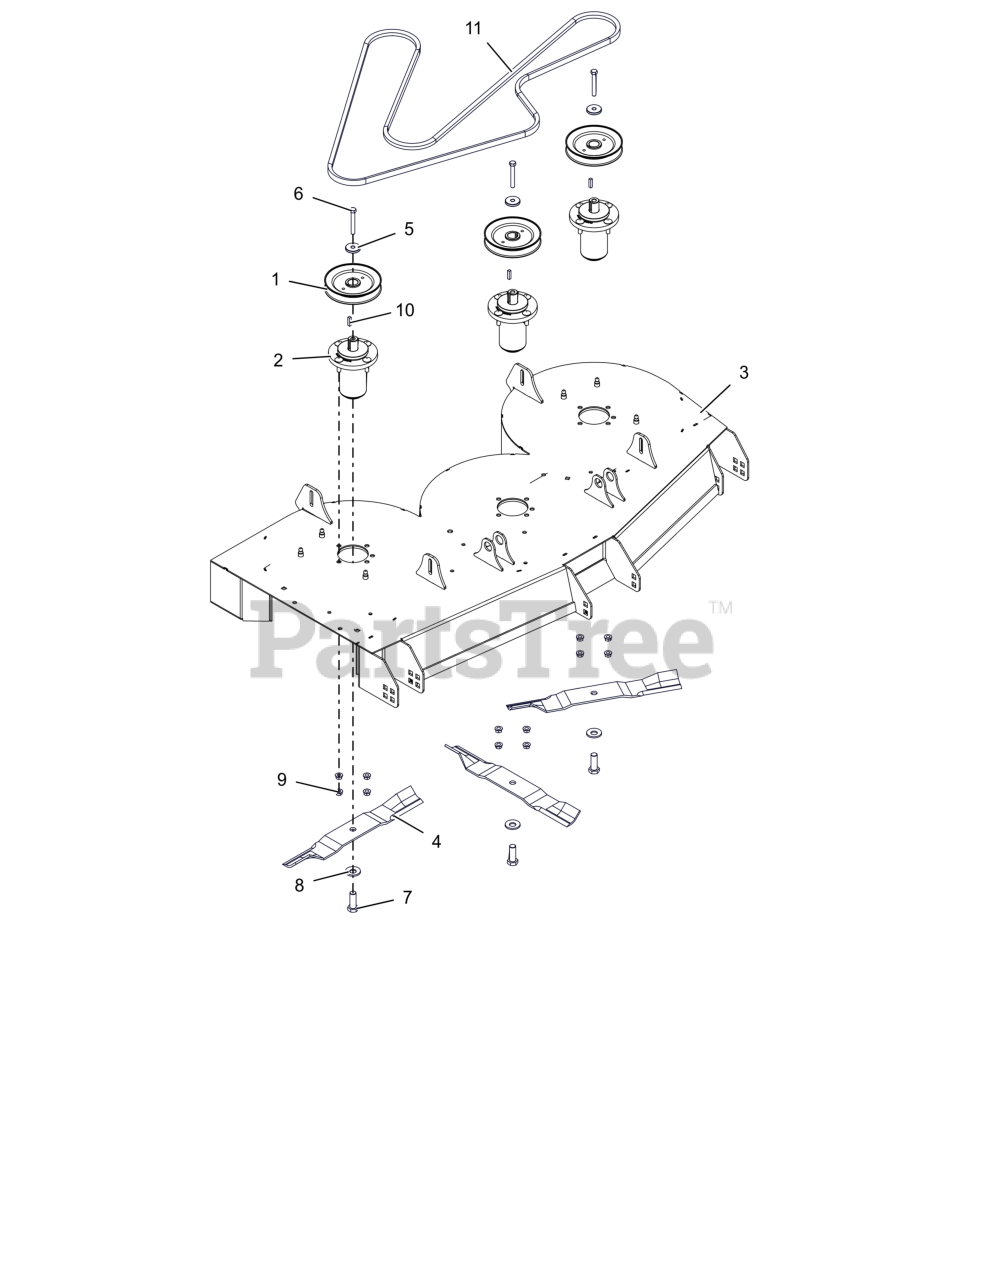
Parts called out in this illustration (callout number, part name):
1	PULLEY- V-1.000 ID X 5.750 OD
2	ASM, MAINT FREE ALUM SPINDLE
3	52 DECK WLDMT W/SAFETY DECALS
4	BLADE, 18"
5	RETAINER, SHEAVE
6	BLT, HEX .38-16X2.75 G8 ZCC
7	BLT, HEX .62-18X1.75 G8 ZCC
8	WSHR-BLVL .669X1.535X.138
9	NUT-LK-CTR-FLG .375-16 GF ZCC
10	KEY, SQ .25X.25X1.00 RC 40-50
11	V-BELT, B SECTION RAW EDGE
